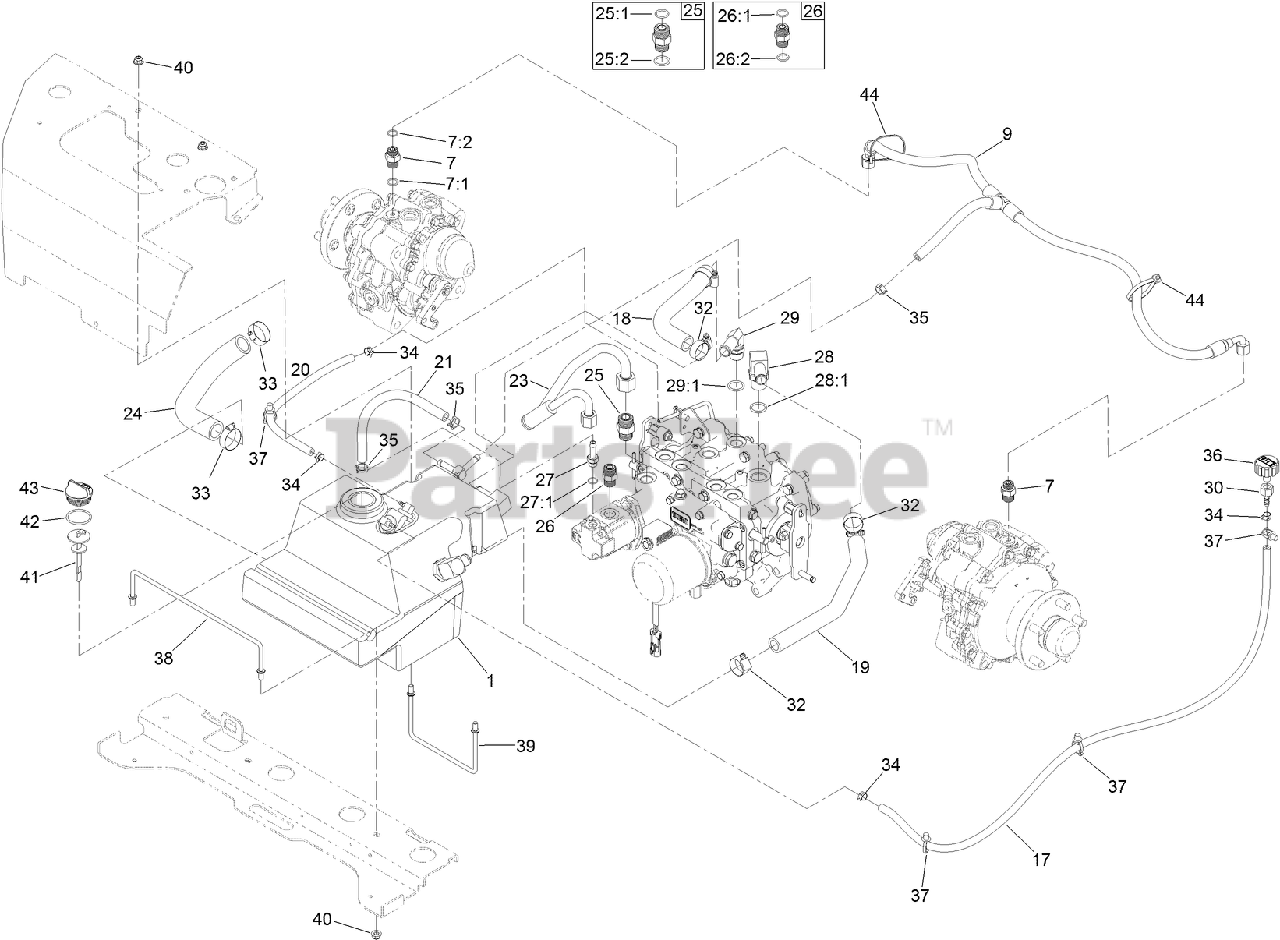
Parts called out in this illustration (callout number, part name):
1	HYD RESERVOIR ASM
7	FITTING-STRAIGHT
7:1	O-RING
7:2	O-RING
9	TEE HOSE ASM
18	HOSE-RETURN
19	HOSE-RETURN
23	TUBE ASM
24	HOSE-SUCTION
25	FITTING-STRAIGHT
25:1	O-RING
25:2	O-RING
26	FITTING-STRAIGHT
26:1	O-RING
26:2	O-RING
27	ADAPTER-STRAIGHT
27:1	O-RING
28	FITTING-ELBOW, 90
28:1	O-RING
29	FITTING-90
29:1	O-RING
30	FITTING-STRAIGHT
32	CLAMP-HOSE
33	CLAMP-HOSE
34	CLAMP-HOSE
35	CLAMP-HOSE
36	BREATHER
37	CLIP-TIE
38	ROD-SUPPORT, HYD TANK
39	ROD-SUPPORT, HYD TANK
40	NUT-HF, NI
41	DIPSTICK
42	O-RING
43	PLUG-PLASTIC
44	TIE-PLASTIC
